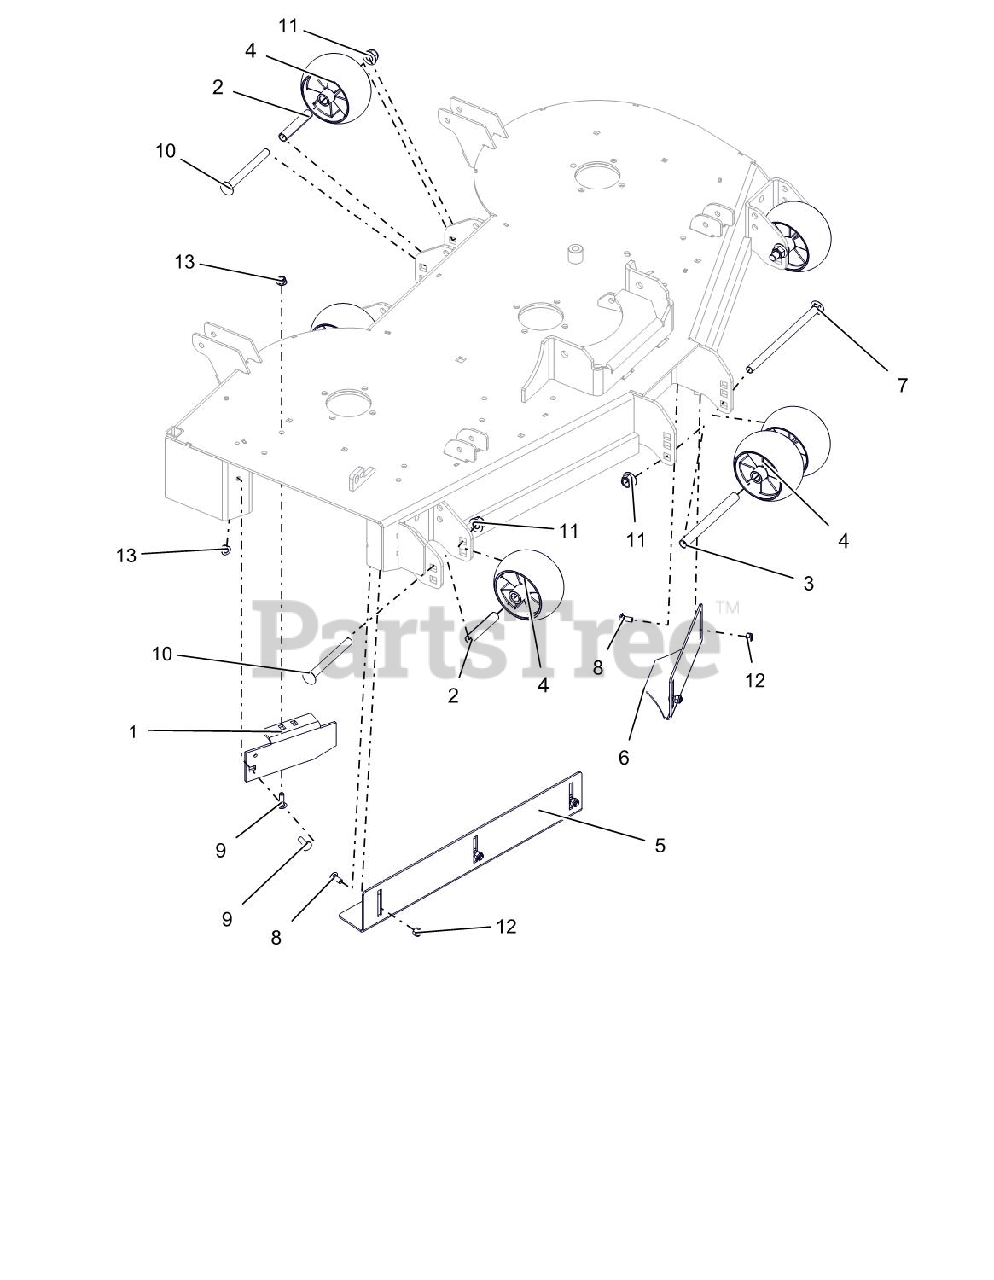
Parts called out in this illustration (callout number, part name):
1	44"-48" REAR DISCH BAFFLE -RED
2	SPACER, .510X.625X3.35
3	SPACER, .510X.625X6.50
4	ANTI-SCALP WHEEL - 5X3 CTR
5	BAFFLE-48" RH VACUUM
6	BAFFLE-44"/48" LH VACUUM
7	BLT-RDHDSQNK .50-13X8.50 G5YZ
8	BLT-RDHDSQNK .31-18X.75 G5YZ
9	BLT-RDHDSQNK .31-18X1.00 G5YZ
10	BLT-RDHDSQNK .50-13X5.00 GR5YZ
11	NUT-LK-NYL-FLG .50-13 YWZC
12	NUT-LK-NYL .312-18 YWZC
13	NUT-LK-NYL-FLG .31-18 YWZC
